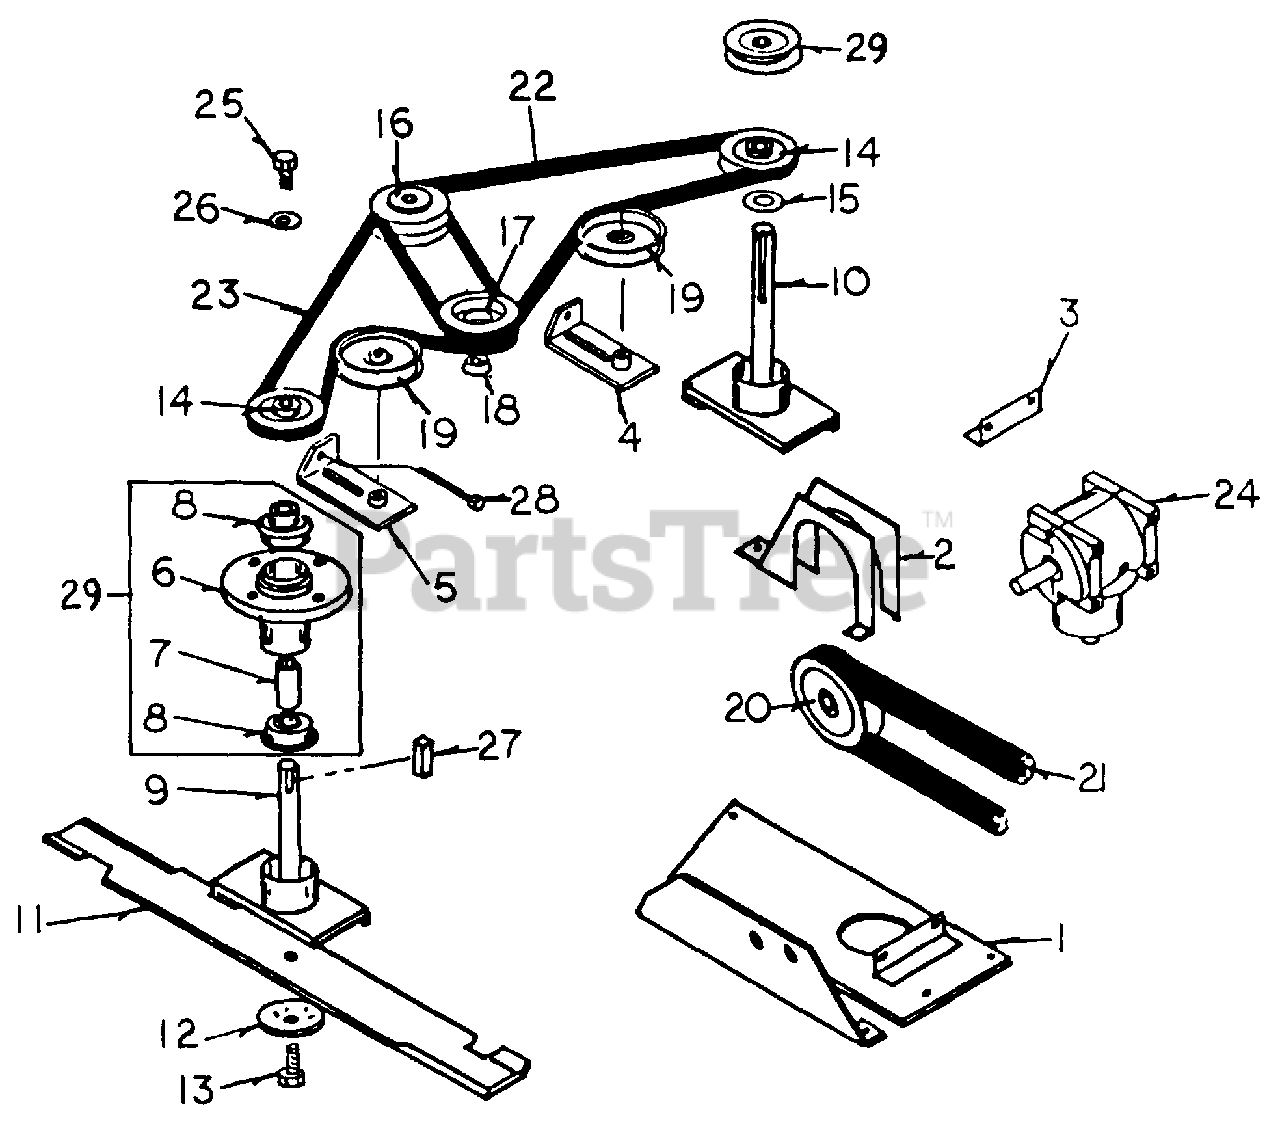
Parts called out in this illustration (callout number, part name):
3	Gearbox Mount Angle
4	Belt Tightener
5	Belt Tightener
6	Spindle Housing
7	Spindle Spacer
8	Spindle Bearing
9	Spindle Shaft
13	Hex Bolt, 3/8-24 x 1 1/4", GR5
14	Spindle Pulley
16	Spindle Pulley, Double A
17	Gearbox Pulley, Output
18	Hub
20	Gearbox Pulley, Input
21	Deck Drive Belt
22	Deck Belt
25	Hex Ny-Lock Bolt, 5/16-24 x 3/4" GR5
26	Washer, 5/16", 10 GA
27	Key, 3/16" x 1"
28	Hex Tap Bolt, 1/4-20 x 4"
29	Spindle Housing Assembly
